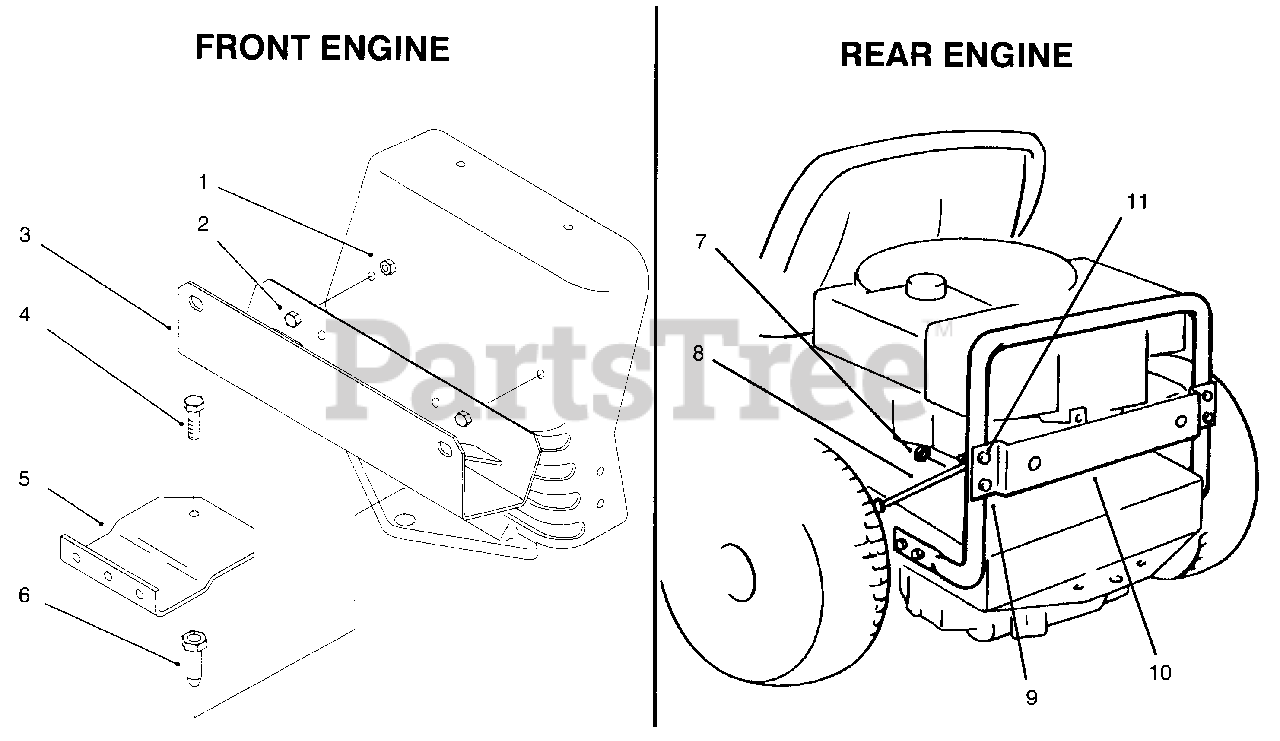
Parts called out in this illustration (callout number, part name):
2	Capscrew
3	Bracket-Channel
4	Capscrew
5	Bracket-Bagger Mounting
6	Pin-Mounting, Lower
8	Brace-Bagging
9	Screw-Cap
10	Plate-Bagging Kit
11	Screw-Cap
